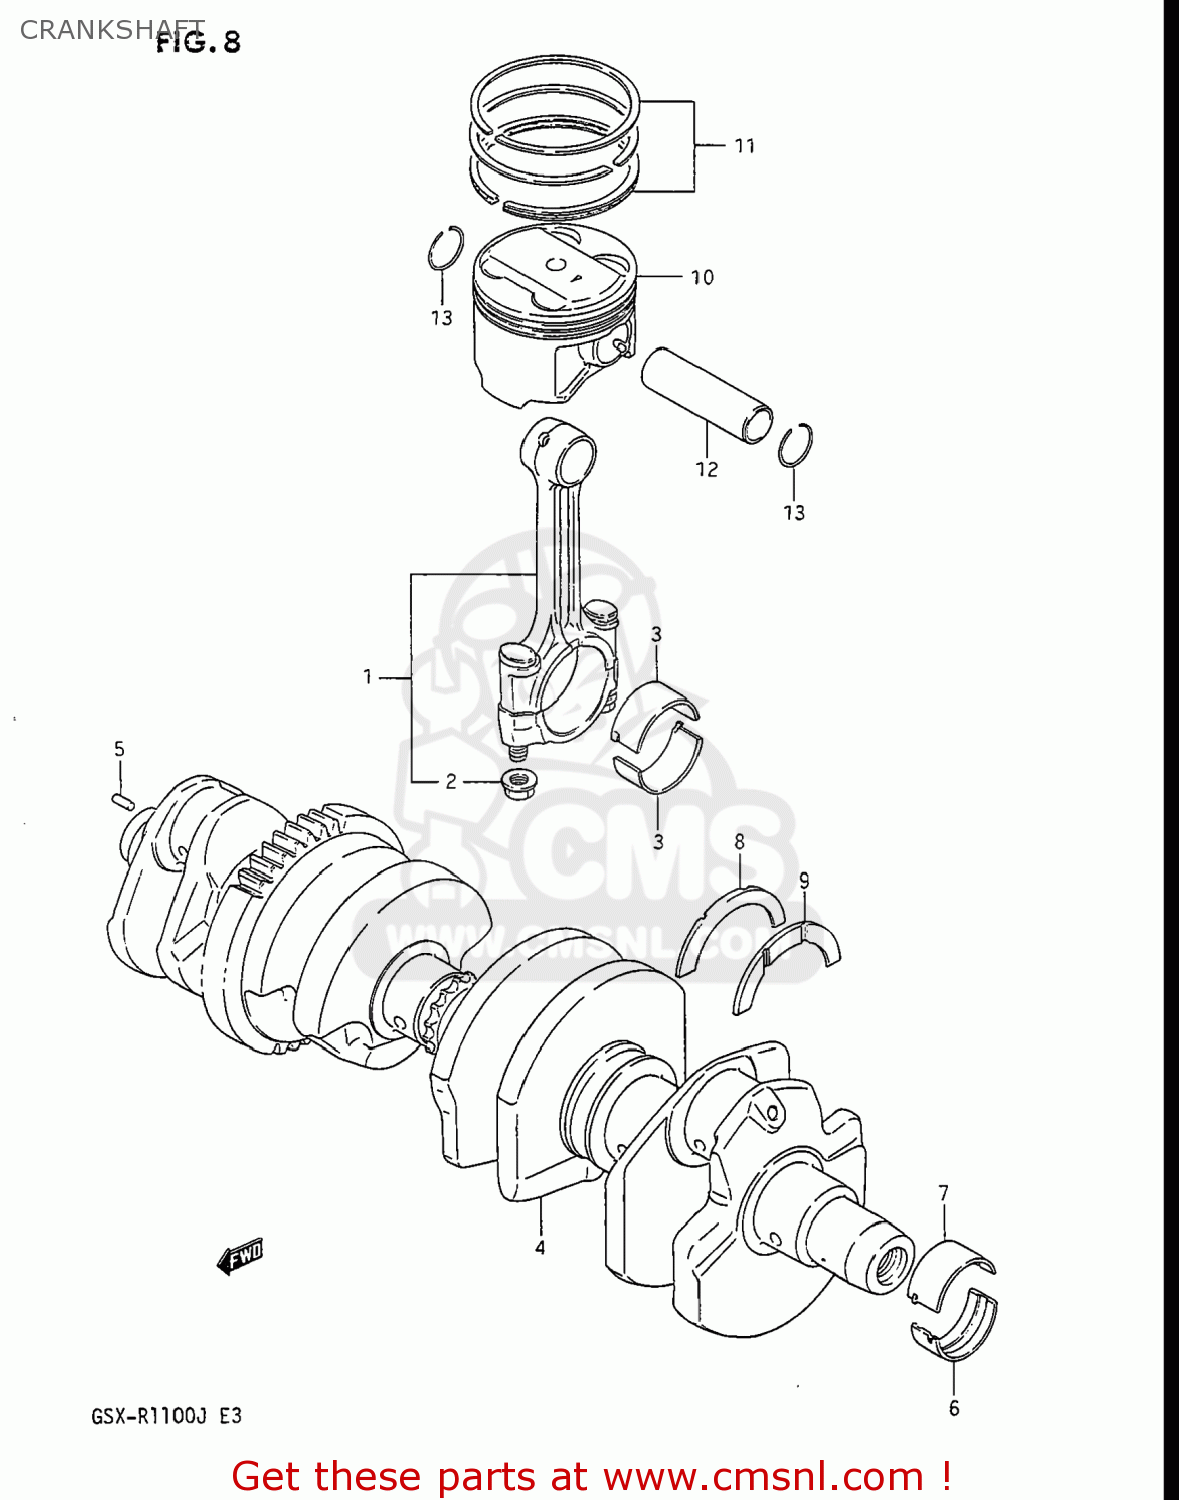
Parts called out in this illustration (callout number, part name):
1	CONNECTING ROD ASSEMBLY
2	NUT
3	BEARING,CRANK PIN
4	CRANKSHAFT
5	PIN
6	BEARING,CRANKSHAFT LWR
7	BEARING,CRANKSHAFT UPR
8	PLATE,CRANK THRUST
9	PLATE,CRANK THRUST
10	PISTON (STD)
11	RING SET,PISTON
12	PIN,PISTON
13	CIRCLIP,PISTON PIN
